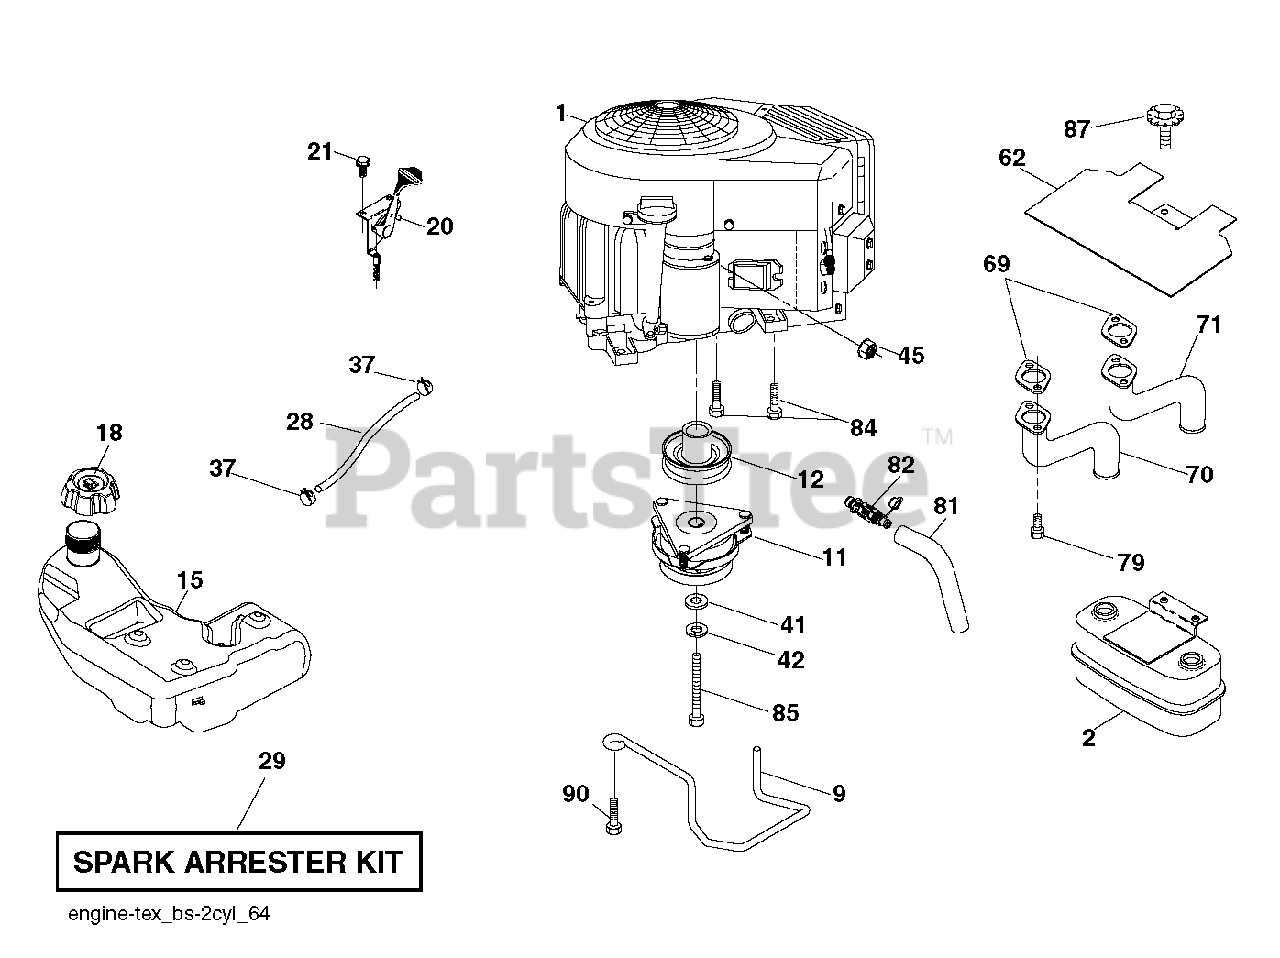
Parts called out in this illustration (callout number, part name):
2	MUFFLER.TWIN.CYL.LOW.TONE
9	KEEPER.BELT.ENGINE.4.2
11	CLUTCH.ELECTRIC.LT.48"*
12	PULLEY.ENGINE.TUFFTORQ
15	TANK.ASSY.3.GAL.EPA
18	CAP.ASM.FL.RITCH.3"E10.SYM.498
20	CONTROL.TH/CK.COBRA.B&S.TWN.
21	SCREW.#10 X 0.750.BOS
28	LINE.FUEL.64"REAR.EMIS
29	KIT.SPARK ARRESTOR 794945 B&S
37	HOSE CLAMP
42	LOCKWASHER
45	NUT
62	RP SHIELD HEAT MUFFLER
69	GASKET.MUFFLER
70	RP.EXHAUST.TUBE.LH.BS/TWIN
71	EXHAUST.TUBE.RH.BS/TWIN
79	SCREW.SOCKET.HEAD.5/16-18
81	TUBE, DRAIN OIL ASM.
82	PLUG DRAIN OIL EASY
84	SCREW.3/8-16
85	BOLT HEX 7/16-20X4-1/4"
87	BOLT, 5/16-18 X 1 3/4
90	SCREW 3/8-16X1
